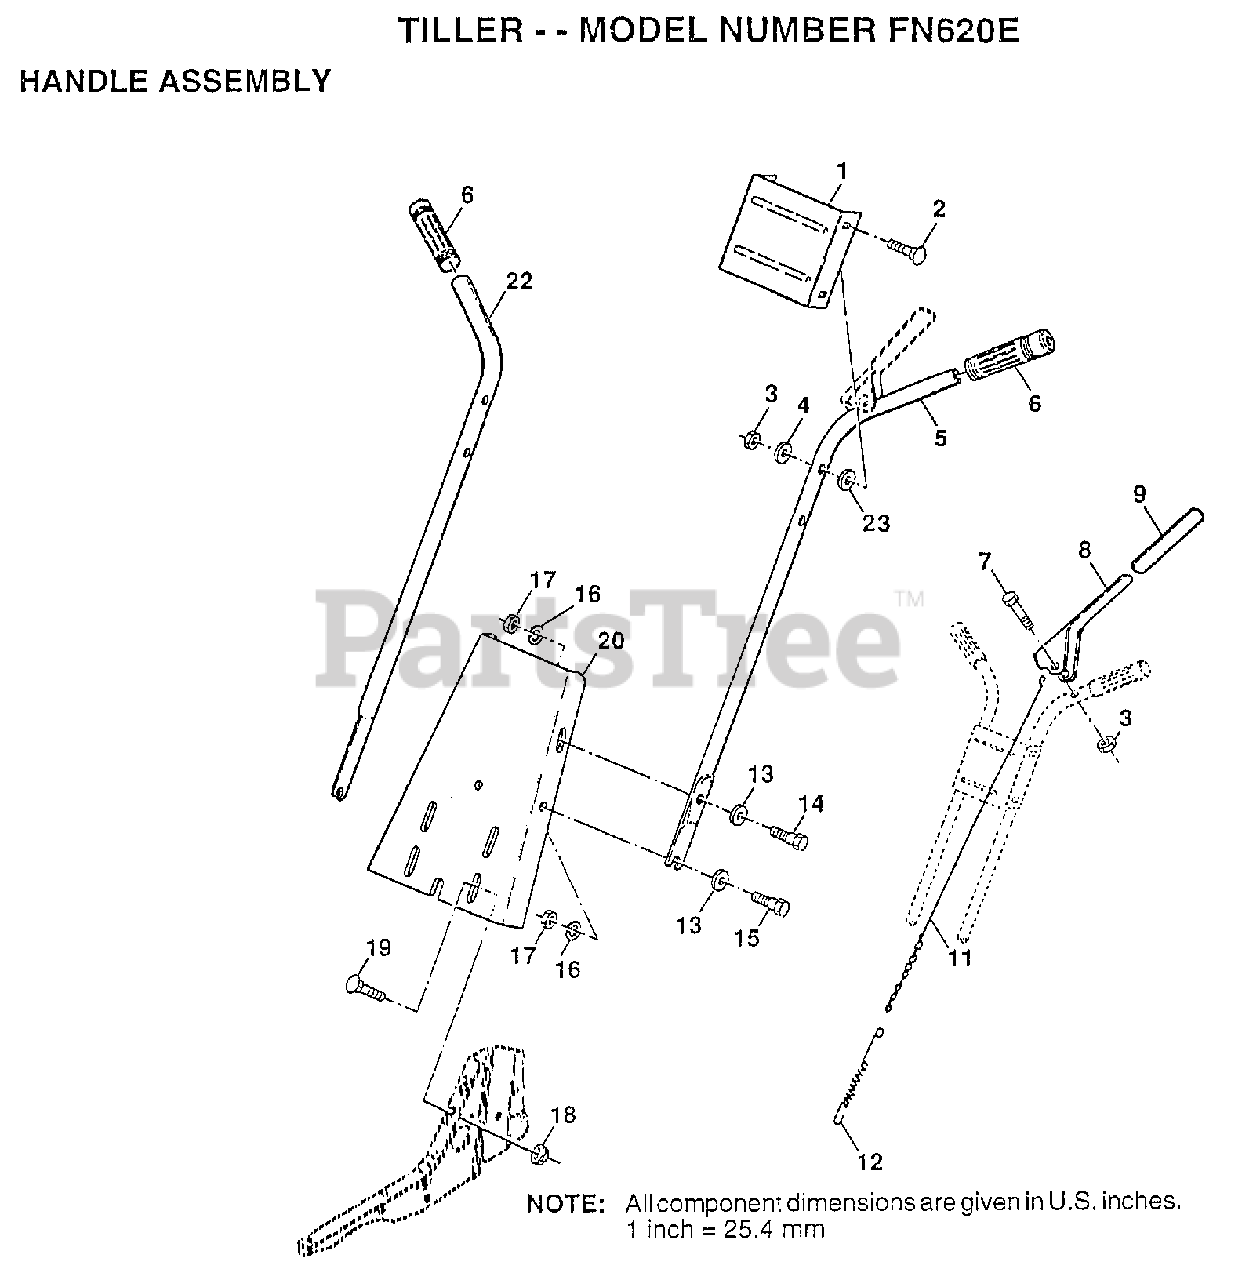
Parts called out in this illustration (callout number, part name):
1	HANDLE BRKT
2	BOLT
4	WASHER
5	HANDLE LH
7	BOLT.HEX.5/16-1.5
9	GRIP T
12	SPRING EXT TI
13	WASHER
15	BOLT
16	LOCKWASHER
17	NUT.HEX.5/16-18
18	NUT
19	BOLT
20	PANEL.HANDLE.TILL
22	HANDLE RH
23	WASHER
